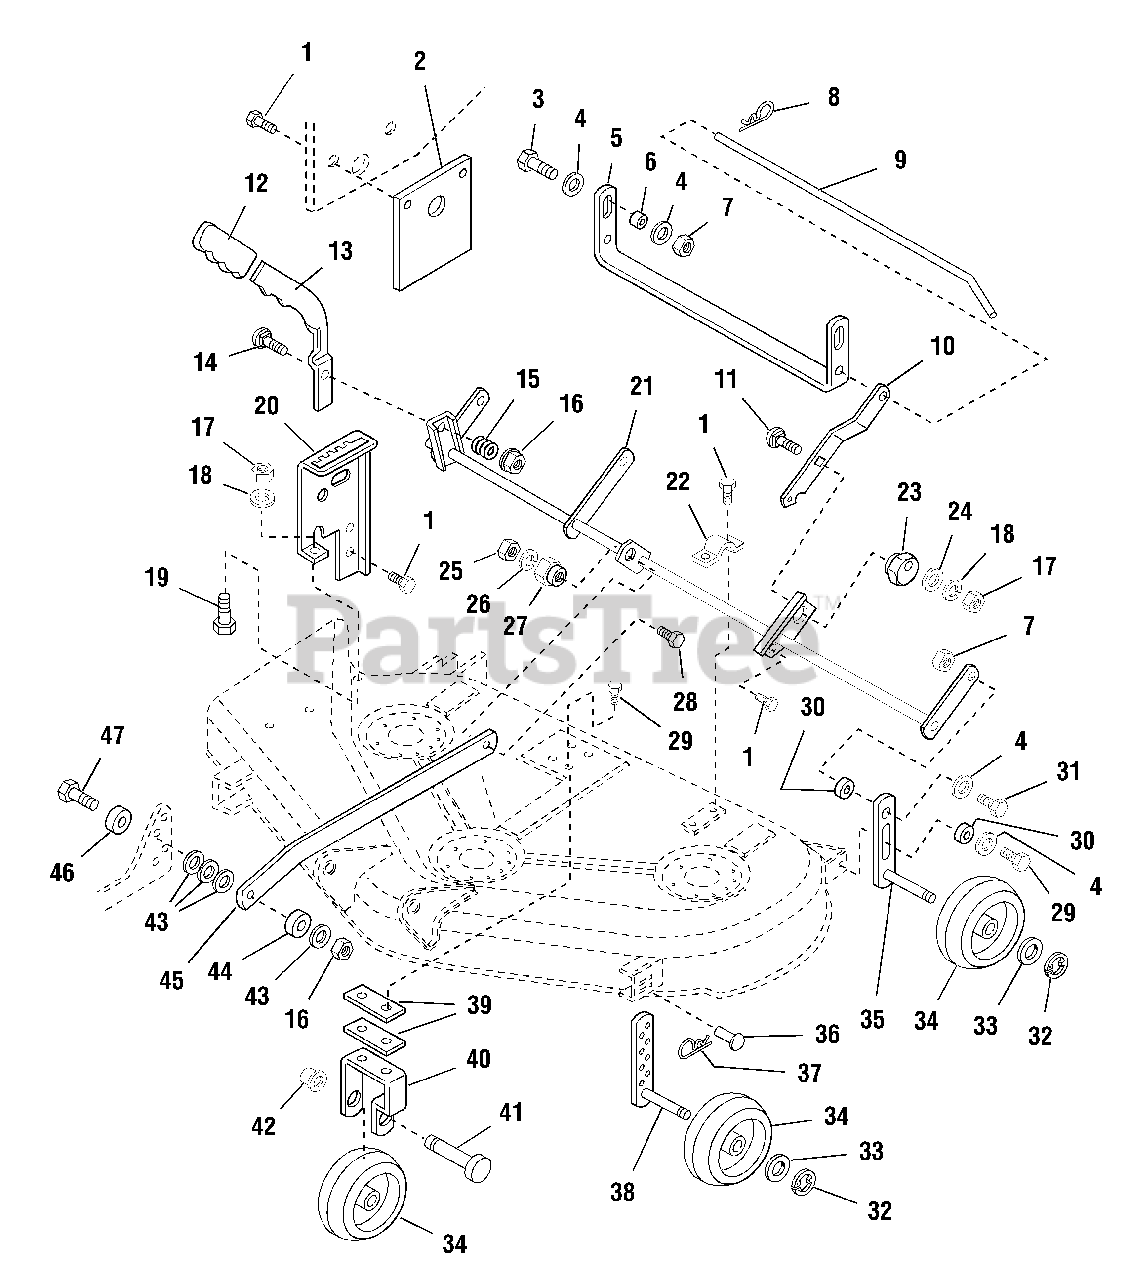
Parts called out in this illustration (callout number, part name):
1	CAPSCREW, Hex Hd, Taptite, 5/16 x 3/4
2	BRACKET, Upstop
3	CAPSCREW, 5/16-18 x 1-1/4
4	WASHER, 5/16
5	BRACKET, "U"
7	NUT, Hex Lock, 5/16-18
8	SPRING CLIP
9	ROD, Transport
10	ARM, Rear
11	CARRIAGE BOLT, 5/16-18 x 1-1/4
13	ARM, Adjustment
14	CARRIAGE BOLT, 3/8-16 x 1-3/4
16	NUT, Hex Flange Lock, 3/8-16
17	NUT, Hex, 5/16-18
18	LOCKWASHER, 5/16
19	CAPSCREW, Hex Hd, 5/16-18 x 3/4
20	QUADRANT BRACKET, Mower Height Adjust
21	ARM ASSEMBLY, Rocker
22	STRAP
24	WASHER
25	NUT, Hex, 3/8
26	WASHER, Lock, 3/8
27	NUT, Hex Adjusting, .99 DIA .687
28	CARRIAGE BOLT, 3/8-16 x 1-1/2
29	CAPSCREW, Hex Hd, Taptite 5/16-18 x 1.0
31	CAPSCREW, 5/16-18 x 1.0
32	E-RING, 1/2
33	WASHER, 1/2
34	WHEEL, Gauge
35	ARM ASSEMBLY
37	CLIP, Hairpin
38	ARM ASSEMBLY, Adjustable
39	STRAP
40	BRACKET, Gauge Wheel
41	ROD, Mower Hitch
42	NUT, Push, 1/2
43	WASHER, 3/8
47	CAPSCREW, 3/8-16 x 1-1/4
